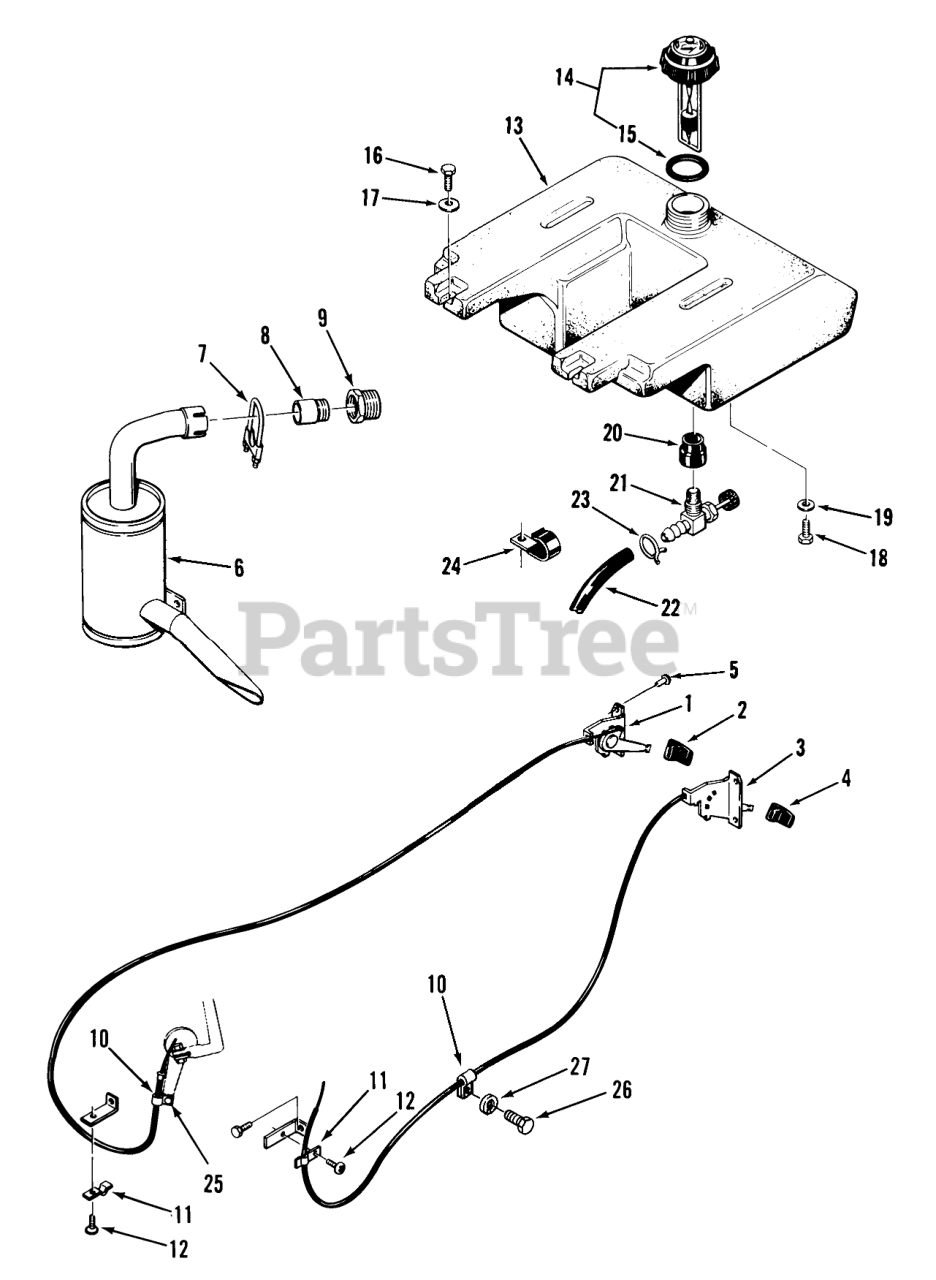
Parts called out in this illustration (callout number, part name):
1	THROTTLE CONTROL
2	KNOB-THROTTLE
3	CONTROL-CHOKE
4	KNOB-CHOKE
5	RIVET-4
6	MUFFLER ASSEMBLY
7	ASSY-MUFFLER CLAMP
8	NIPPLE- 1X2 SPECIAL
9	REDUCER 1 1/4-1
10	Clip
11	CLAMP-CABLE
12	SCREW
13	TANK-FUEL
14	ASSY-GAUGE CAP
15	GASKET-GAS CAP
16	Bolt
17	Washer
18	Bolt
19	Lockwasher
20	BUSHING
21	VALVE-FUEL
22	Fuel Line
23	Clamp
24	CLIP
25	Screw
26	Bolt
27	Washer
